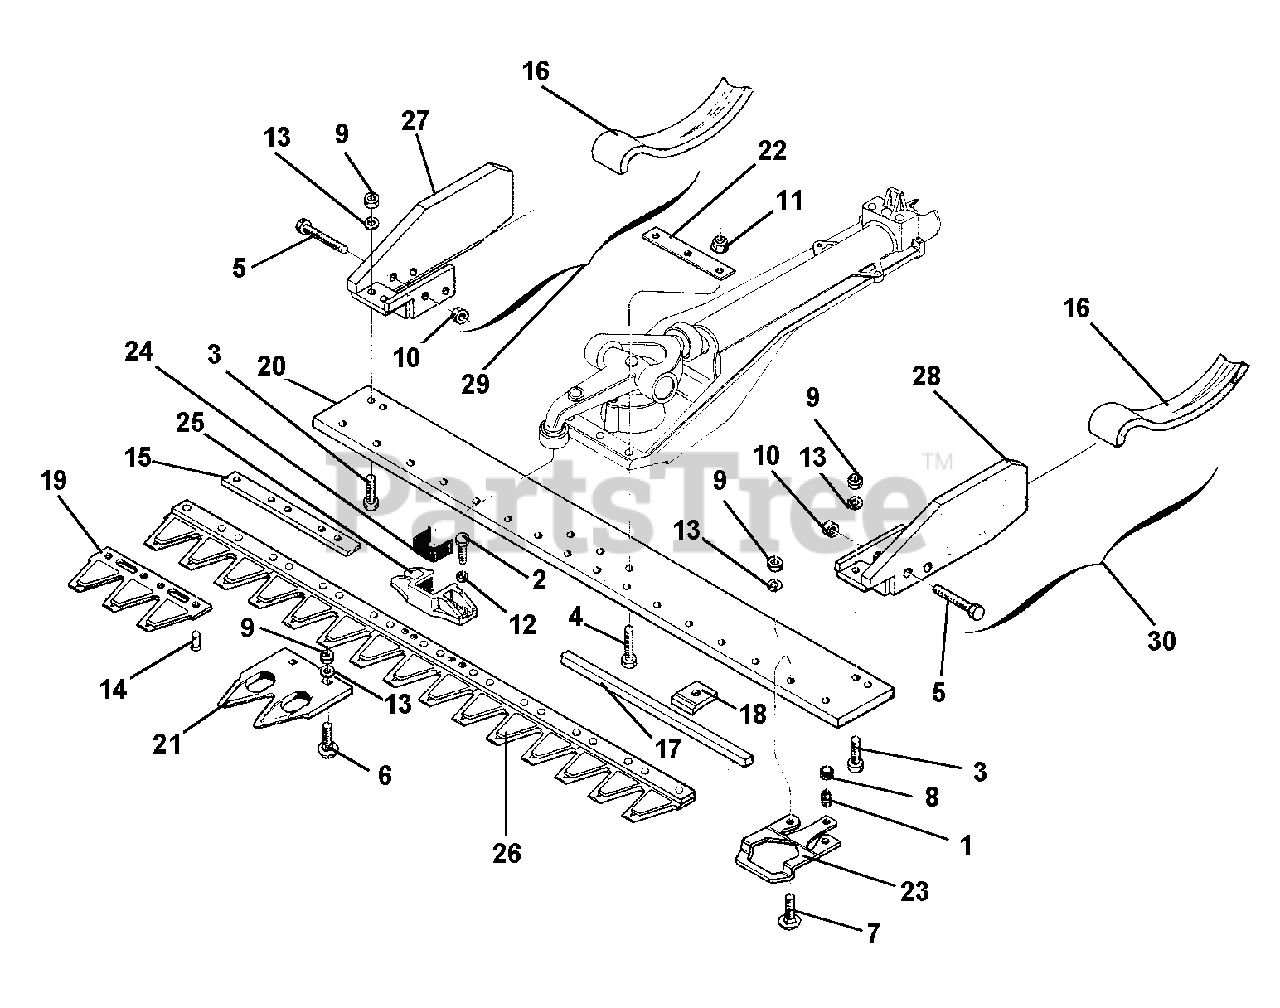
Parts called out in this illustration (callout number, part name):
1	SCREW M8 X 14
2	SCREW TE M6 X 16
3	SCREW M8 X 25
4	SCREW M8 X 35
5	SCREW M8 X 80
6	SCREW M8 X 25
7	SCREW M8 X 30
10	NUT, SELF LOCKING M8
11	NUT, SELF LOCKING M8
12	WASHER, LOCK 6.4
13	WASHER, LOCK 8.4
14	RIVET 5.3 X 14
15	BLADE STRIP 32"
17	BLADE GUIDE
18	GUIDE HOLDER
19	THREE BLADE SECTION
20	CENTRAL BAR 32"
21	DOUBLE BLADE
22	SUPPORT PLATE
23	BLADE HOLDER
25	NYLON COUPLING
26	BLADE SECTION 32"
27	RIGHT SKID MOUNT
28	LEFT SKID MOUNT
29	RIGHT SKID ASSEMBLY
30	LEFT SKID ASSEMBLY
